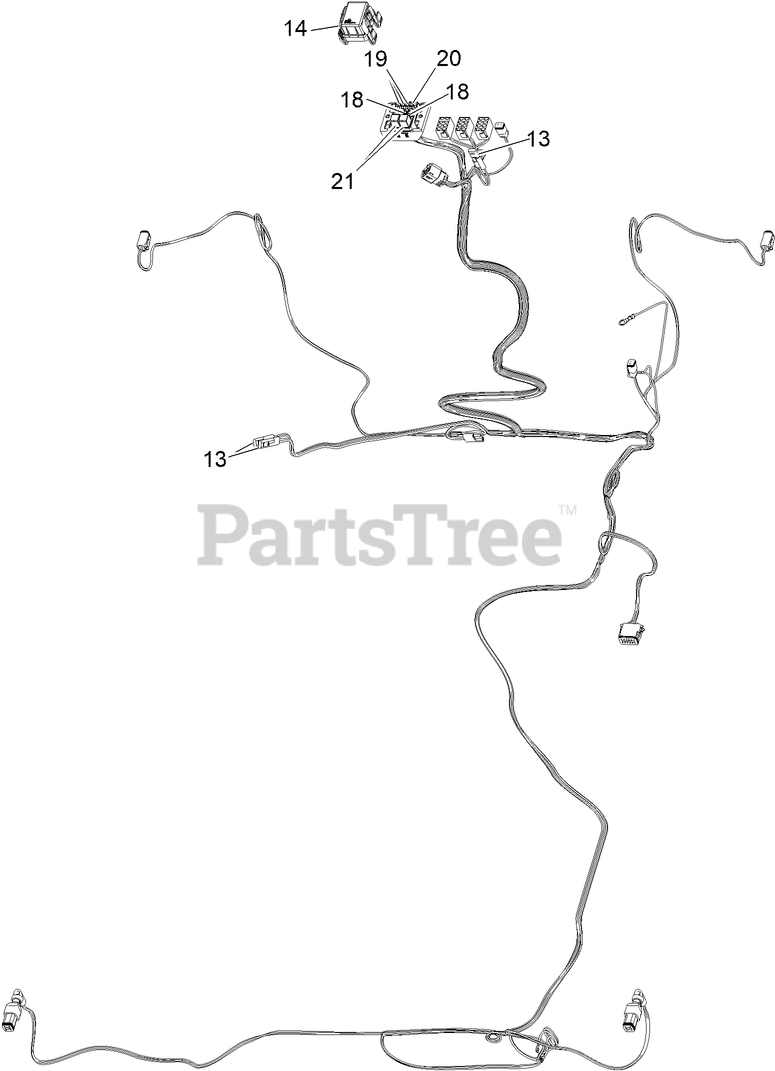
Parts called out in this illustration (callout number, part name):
13	CAP-PLUG
14	COVER-FUSEBLOCK
18	FUSE-MINI BLADE, 2 AMP
19	FUSE-MINI BLADE, 5 AMP
20	FUSE-MINI BLADE, 10 AMP
21	RELAY-MICRO
